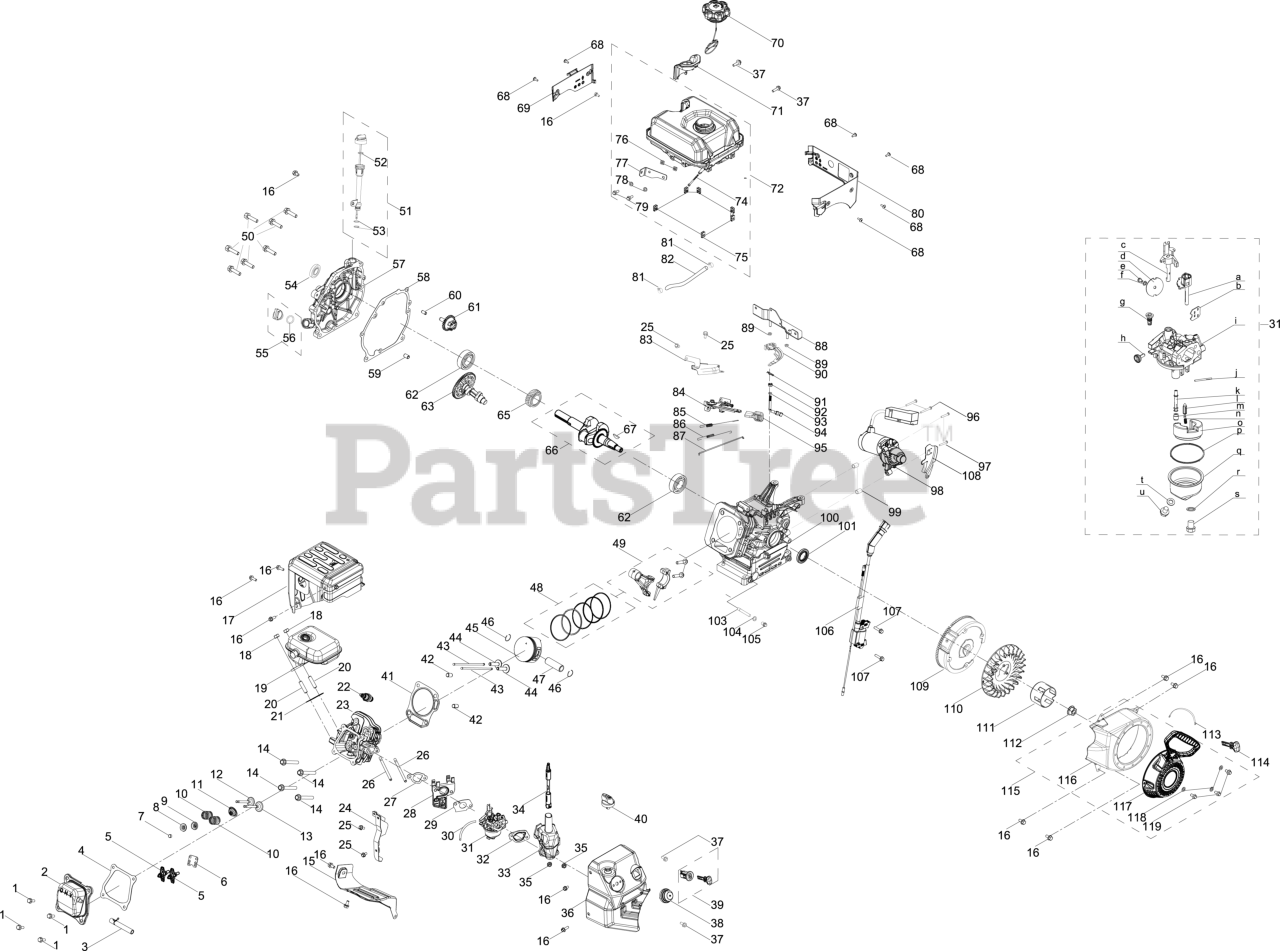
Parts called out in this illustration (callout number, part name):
1	BOLT M6x16
2	VALVE COVER
3	BREATHER HOSE
4	VALVE COVER GASKET
5	ROCKER ARM KIT
6	ROCKER ARM BASE
7	EXHAUST VALVE ADJUSTER
8	EXHAUST VALVE SPRING RETAINER
9	INTAKE VALVE SPRING RETAINER
10	VALVE SPRING
11	INTAKE VALVE SEAL
12	EXHAUST VALVE
13	INTAKE VALVE
14	FLANGE BOLT M8-1.25 x 55
15	SHROUD
16	FLANGE BOLT M6-1 x 12
17	MUFFLER GUARD
18	NUT M8
19	MUFFLER
20	STUD M8 X 34
21	MUFFLER GASKET
22	SPARK PLUG (F6RTC/RN11YC/BPR6ES)
23	CYLINDER HEAD
24	SNOW GUARD
25	FLANGE BOLT M6-1 x 12
26	STUD M6 x 90
27	CARBURETOR INSULATOR GASKET
28	INSULATOR
29	CARBURETOR GASKET
30	PRIMER HOSE
31	CARBURETOR (KEIMA)
31	Carburetor
32	CARBURETOR GASKET PLATE
33	HEATER BOX
34	CHOKE LEVER
35	NUT M6
36	CONTROL PANEL
37	BOLT M6-1 x 18 GR8.8
39	ENGINE KEY SWITCH ASSEMBLY
40	CHOKE LEVER
41	CYLINDER HEAD GASKET
42	PIN (10MMx16MM)
43	PUSH ROD
45	PISTON
46	PISTON PIN SNAP RING
47	PISTON PIN
48	PISTON RING 4PC SET
49	CONNECTING ROD
50	BOLT M8-1.25 x 32 GR5.8
51	DIPSTICK ASSEMBLY
53	OIL FILL TUBE O-RING
54	OIL SEAL
55	OIL PLUG
56	O-RING 15.8 x 2.5
57	CRANKCASE COVER
58	CRANKCASE GASKET
59	DOWEL PIN 9 X 14
60	DOWEL PIN 7 X 14
61	GOVERNOR GEAR
62	BEARING
63	CAMSHAFT
65	DRIVE TIMING GEAR
66	CRANKSHAFT
67	WOODRUFF KEY
68	BOLT: M5 x 14
69	FUEL TANK SHROUD (RH)
70	FUEL CAP
71	DECORATIVE COVER
72	FUEL TANK
74	FUEL FILTER
75	FUEL TANK MOUNT THREADED TAB
76	NUT M6
77	FUEL TANK MOUNT TAB
78	WASHER 6.5 x 1.5 x 12
79	BOLT M6 x 20
80	DECORATIVE SHEET (LH)
81	CARBURETOR HOSE CLAMP
82	FUEL HOSE 6.3 x 12.5 x 162
83	GOVERNOR SHIELD
84	THROTTLE CONTROL BRACKET
85	GOVERNOR SPRING
86	THROTTLE SPRING
87	THROTTLE LINKAGE
88	FUEL TANK BRACKET
89	NUT M6
90	GOVERNOR LEVER
91	COTTER PIN
92	OIL SEAL 6x11x4
93	O-RING
94	BOLT M8-1.25 x 32 GR5.8
95	THROTTLE CONTROL KNOB
97	BOLT M6 x 32
98	ELECTRIC STARTER
99	DOWEL PIN
100	CRANKCASE
101	OIL SEAL
103	OIL DRAIN PIPE
104	FLAT WASHER
105	DRAIN PLUG M10-1.25x15
106	IGNITION MODULE
107	BOLT M6x25
108	LOWER SHIELD
109	FLYWHEEL
110	COOLING FAN
111	STARTER CUP
112	NUT M14 X 1.5
113	CABLE TIE 3x150
114	IGNITION KEY
115	RECOIL STARTER
116	BLOWER HOUSING
117	RECOIL STARTER ASSEMBLY
118	FLAT WASHER
119	BOLT M6 X 10
